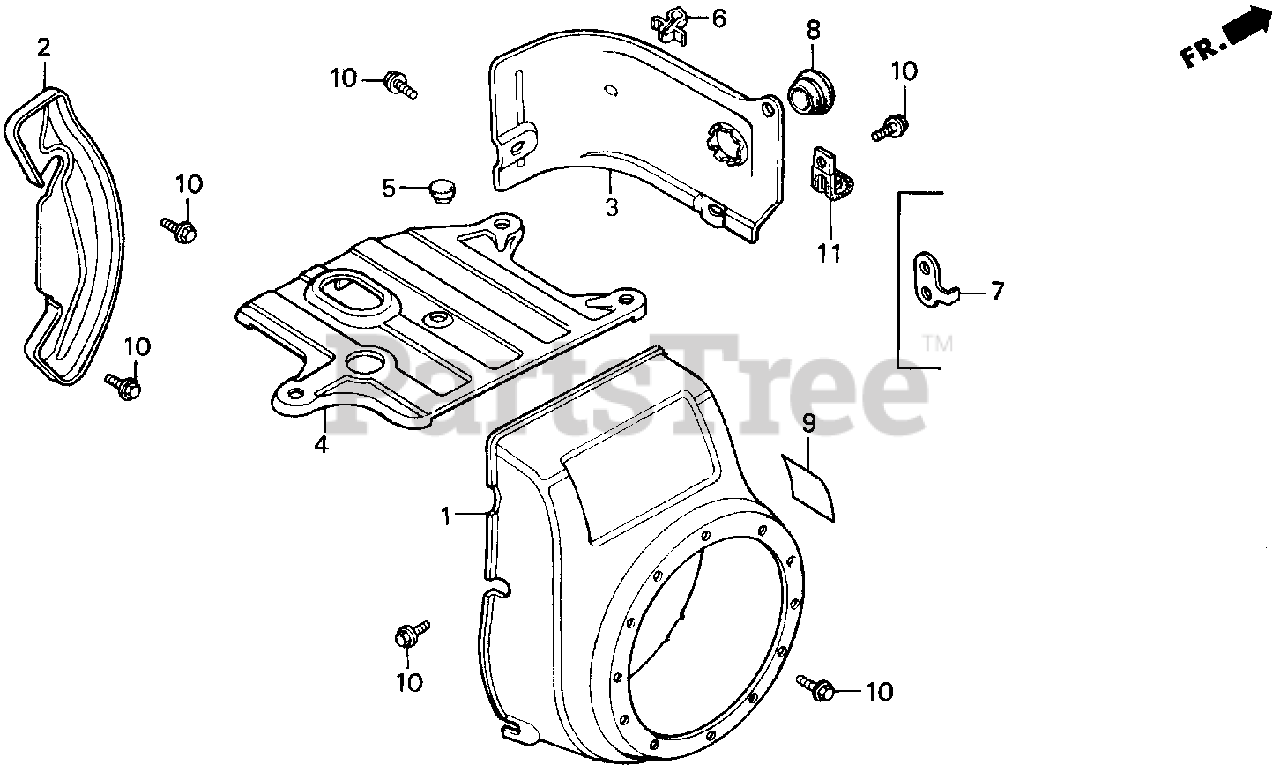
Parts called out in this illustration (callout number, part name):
1	COVER, FAN *R8* (BRIGHT RED)
2	PLATE, SIDE
3	SHROUD *R8* (BRIGHT RED)
4	COVER, TOP *R8* (BRIGHT RED)
6	CLIP, IGNITION WIRE (8MM)
7	STAY, WIRE CLIP (B)
8	GROMMET, DRAIN HOLE
9	MARK, OIL CAUTION
10	BOLT, FLANGE (6X12) (CT200)
